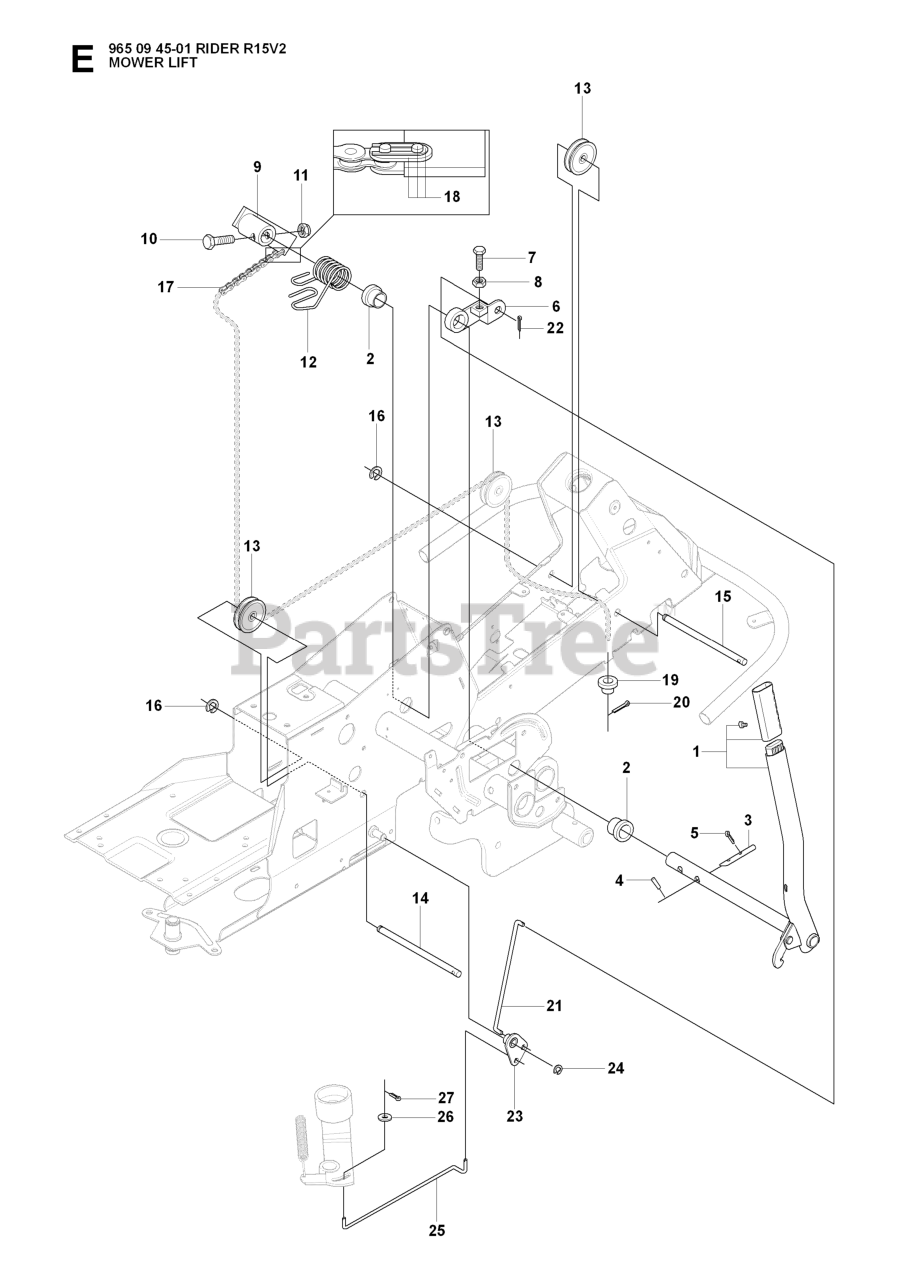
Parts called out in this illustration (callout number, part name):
1	LIFTING LEVER ASSY
2	BEARING FLANGE
3	RP PIN
6	LEVER CLUTCH
8	NUT
20	COTTER PIN
21	CONNECTION ROD
24	RETAINING RING
25	CONNECTION ROD
